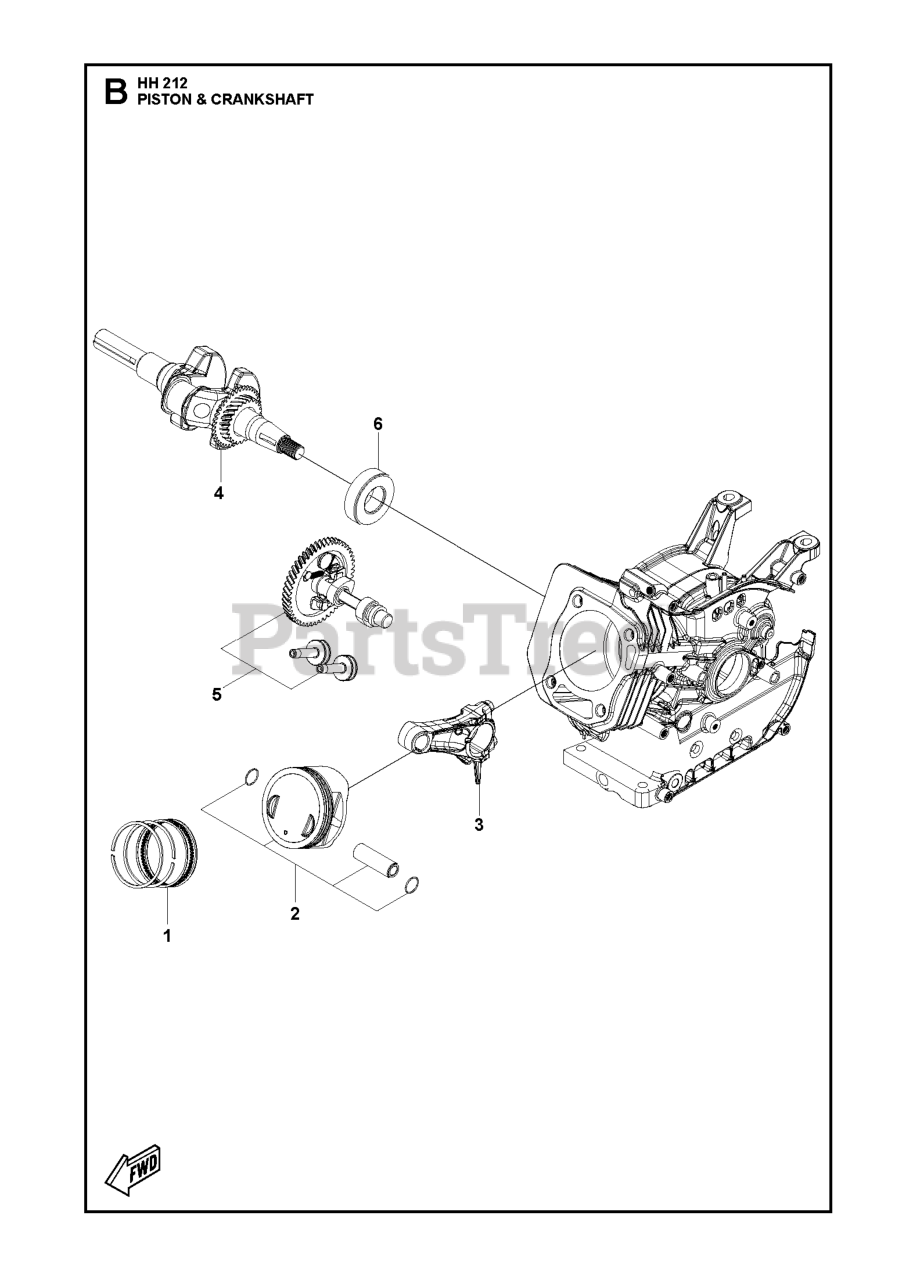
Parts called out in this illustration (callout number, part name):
1	PISTON RING SET
2	PISTON ASSY
3	CONNECTING ROD ASSY
4	CRANKSHAFT
5	CAMSHAFT KIT
6	BALL BEARING
